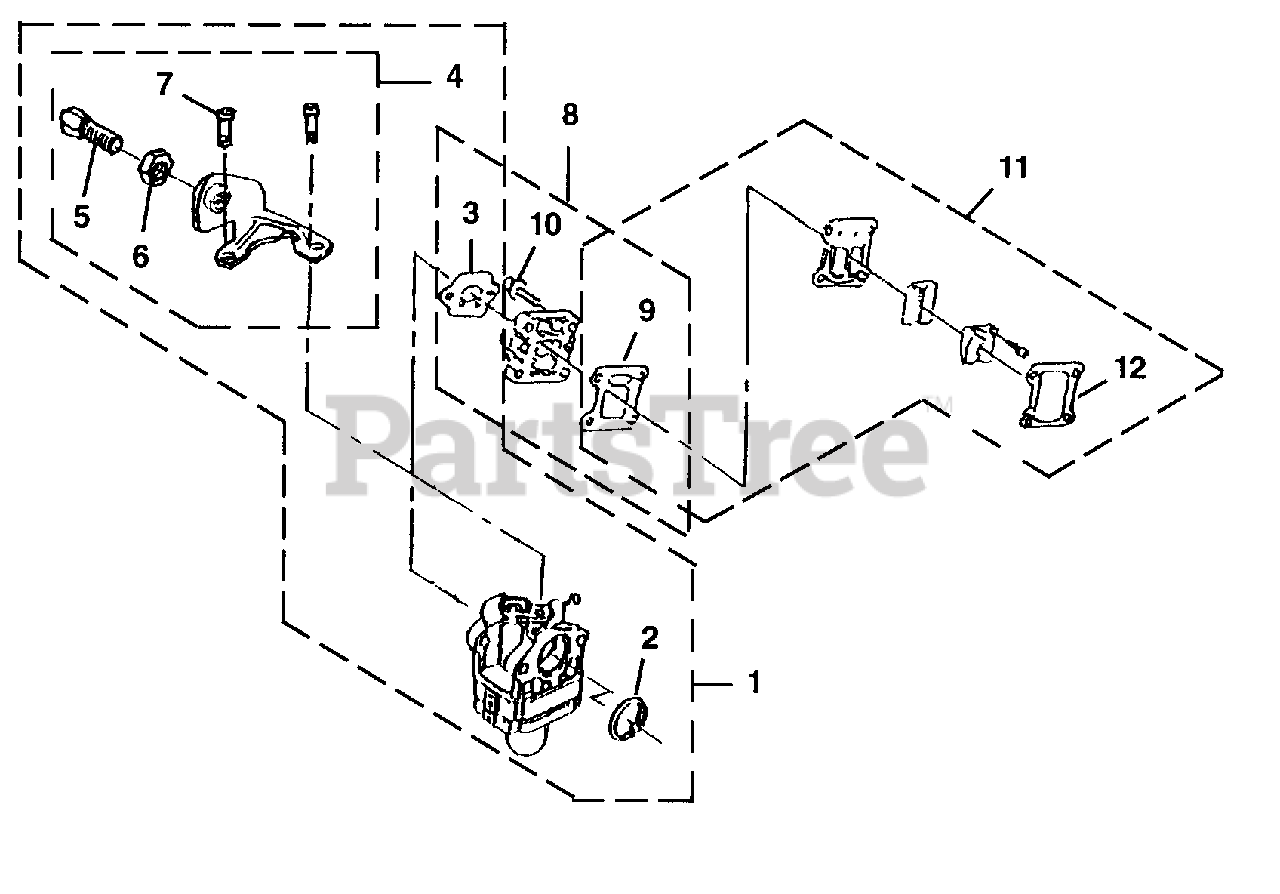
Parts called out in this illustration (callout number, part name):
1	CARBURETOR ASSY
2	RING-Packing
3	GASKET-Carburetor
4	CABLE BRACKET
5	SCREW-Cable Adjust
6	NUT-Cable Adjust
7	SCREW-Throttle Collar
8	HEAT DAM ASSEMBLY
9	GASKET-Heat Dam
10	SCREW-Socket Hd (M5 x 20)
11	REED VALVE ASSY
12	GASKET-Reed Valve
